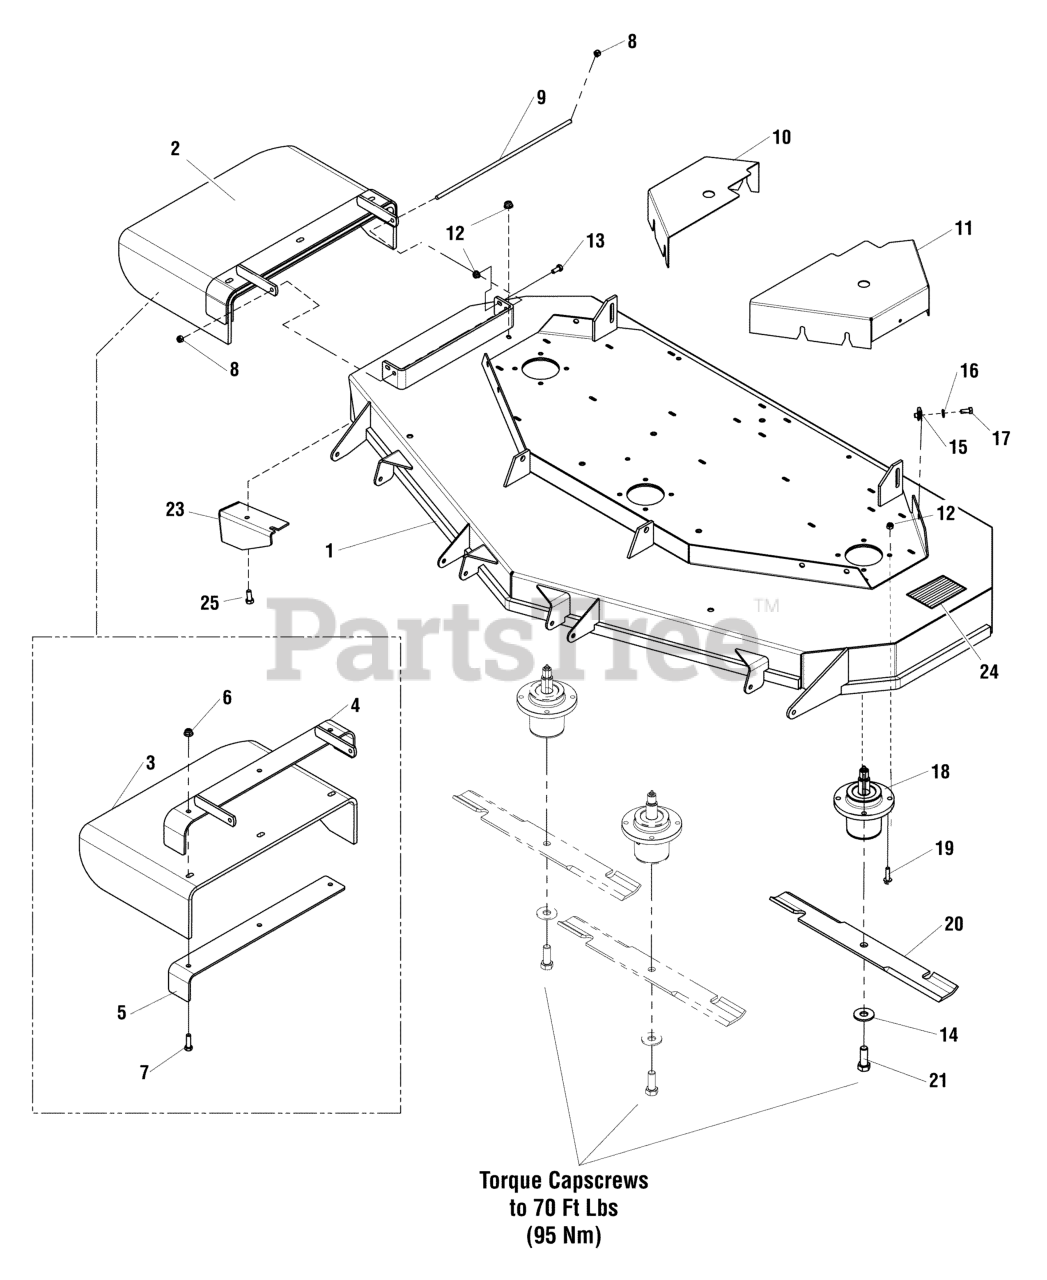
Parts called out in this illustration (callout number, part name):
1	DECK SHELL W/DECALS, 61", IS2000Z
2	61" RUBBER CHUTE ASSEMBLY, Complete
3	CHUTE, DISCHARGE, RUBBER, 61/72, BENT
4	WELD, FRAME, CHUTE, 61 - RED
5	SUPPORT, DISCHARGE CHUTE, 61 - RED
6	NUT, 3/8-16 HEX NYLOCK FLANGE
7	BOLT, 3/8-16 X 1-1/4" GD5 CZ
8	NUT, 5/16-24 HEX NYLON LOCK
9	ROD MOUNT, CHUTE 61"
10	GUARD, 61", RH - RED
11	GUARD, 61 - LH - RED
12	NUT, 5/16-18 HEX NYLOCK FLANGE
13	BOLT, 5/16-18 X 3/4 GD5
14	WASHER, 5/8" GRADE 8, YZ
15	BODY CLIP, 5/16-18-7GA MATERIAL
16	WASHER, 5/16" SAE
17	BOLT, 5/16-18 X 3/4 GD5
18	ASSM, SPINDLE, LOW PROFILE
19	BOLT, 5/16-18 X 1 1/4" FLANGE
20	BLADE, 21"
21	BOLT, 5/8-11 X 1-3/4 GD8
22	WASHER, 5/16" SAE
23	PLATE, DEFLECTOR - BLK
24	SAFETY WALK, 9.75 X 6.00
25	BOLT, 5/16-18 X 3/4, CARRIAGE
